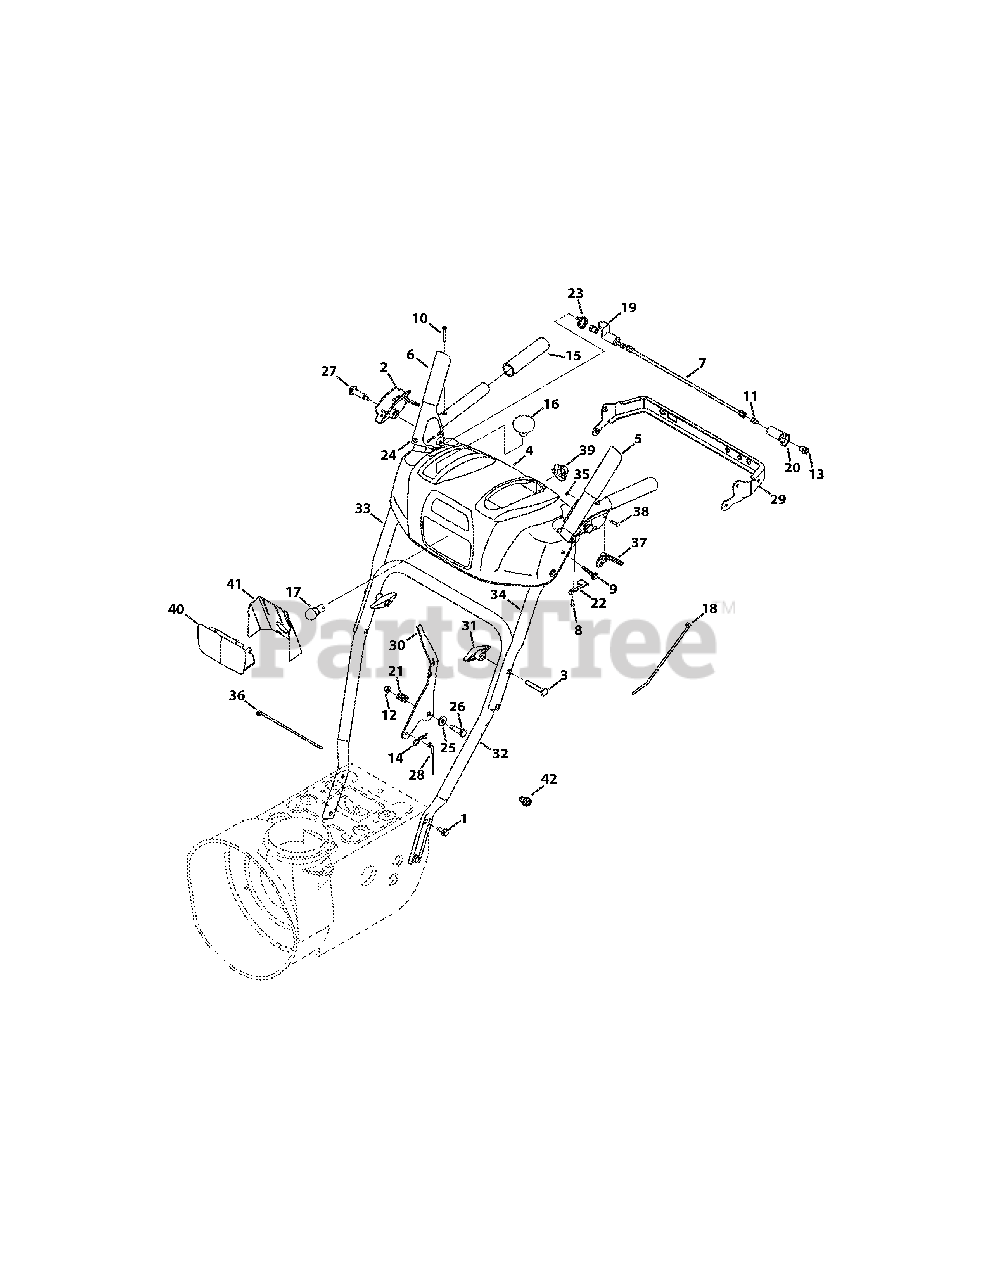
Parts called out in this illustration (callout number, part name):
1	Hex Screw, 5/16-18 x .750
2	Handle Clutch Lock LH Assy
2	Handle Clutch Lock RH Assy
3	Carriage Screw, 5/16-18 x 2.25
4	Handle Panel, includes Ref. 40 & 41
5	Handle Engagement Assembly LH
6	Handle Engagement Assembly RH
8	Screw, 8-16 x 0.50
9	Screw, 1/4-20 x 1.625
10	Screw, 10-24 x 1.375
11	Socket Screw, 1/4-20 x .50
12	Flange Lock Nut, 1/4-20
13	Shoulder Nut, 1/4-20
14	Click Pin, .092 x 1.64
15	Handle Grip (524/526/528 SWE)
16	Shift Knob
18	Cable Tie
20	Clutch Lock Cam
21	Compression Spring
22	Clutch Lock Spring
23	Torsion Spring
24	Rubber Bumper
25	Flat Washer, .385 x .87 x .06
26	Shoulder Screw, .374 x 1.05
27	Shoulder Screw, 1/4-20 x 1.345
28	Speed Cable Selector
31	Wing Knob
32	Lower Handle
33	Upper Handle RH
34	Upper Handle LH
36	Cable Tie
37	Clutch Trigger
39	Light Socket
41	Lens Label
42	Screw, TT, 1/4-20 x .500 (For ground wire)
